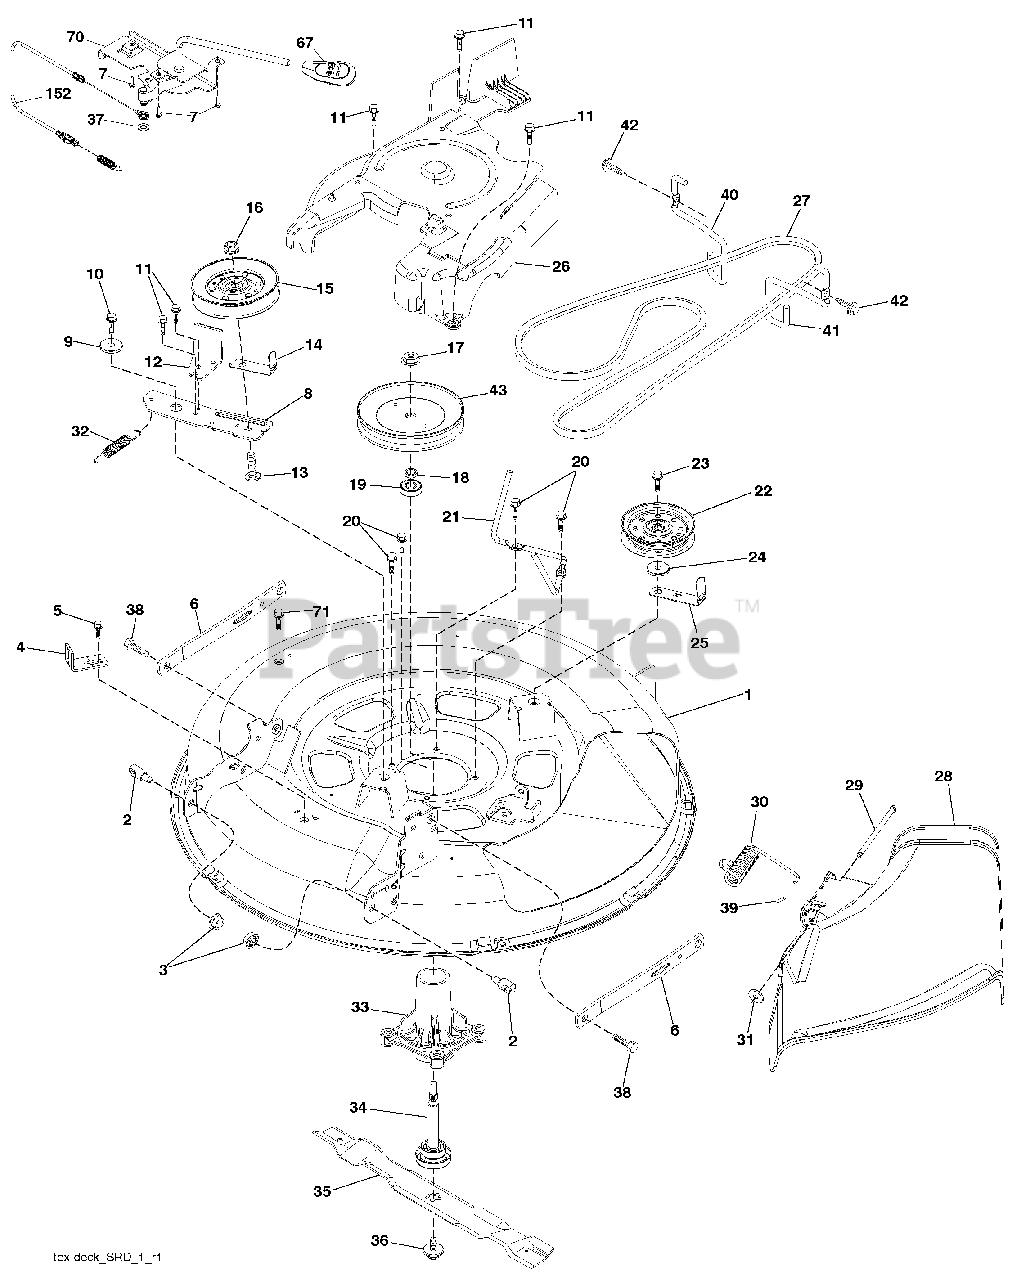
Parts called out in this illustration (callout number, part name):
1	Deck Weldment 30"Srd
2	Stud Fastner w/'d'anti-Rotatio
3	Nut Lock Hex Flange 5/16 - 18
4	Bracket Clutch Cable
5	Bolt 5/16-18
6	Arm Susp Mower Rear Srd
7	Screw #10 x 0.750 BOS Thread
8	Arm Idler 30"Srd
9	Spacer Retainer
10	Screw 3/8 - 16 X 1 Smgml Tap/R Blk
11	Screw Thd Roll 1/4 - 20 X 5/8
12	Arm Brake Mower 38" RH Tex
13	Bolt Carr Sh 3/8 - 16 X 1 - 1/2 Gr5
14	Keeper Belt Idler
15	Pulley Idler V-Groove Dim 4.25
16	Nut Lock FlG 3/8 - 16 unc
17	Nut Flange Lock Top
18	Washer Spacer Mandrel
19	Bearing Ball Mandrel
20	Screw Thd Roll Dod Pt Hex
21	Keeper Belt Mandrel 30"
22	Pulley Idler Flat Unplated
23	Screw Thdrol 3/8 - 16 X 1-3/4
24	Washer 13/32 X 1 - 1/4 X 12 Ga
25	Keeper Belt 30"Srd
26	Cover Mandrel Mwr 30"Black
27	Drive, Belt
30	Spring Torsion
31	Nut Push
32	Spring Return Deck 38/46"
33	Housing Mandrel 4pt Service
34	Shaft Asm Mndrl N/Greaseable 38
35	Blade Mower Bagging Srd
36	Bolt/Washer Asm 7/16 - 20 unf
37	Washer 13/32 x 13/16 x 16 Ga.
38	Bolt Shoulder
39	Cap Sleeve
40	Keeper Belt Engine LH
41	Keeper Belt Engine RH
42	Screw Hexwsh THDR 3/8-16 x 3/4 BL
43	Pulley Mandrel 6 5 Pd 30"
67	Handle clutch cable
70	Clutch Asm. Manual
71	Screw 3/8-16 x 1/2
152	Manual Clutch Cable
152	Mandrel Assembly
152	Replacement Mower Complete
